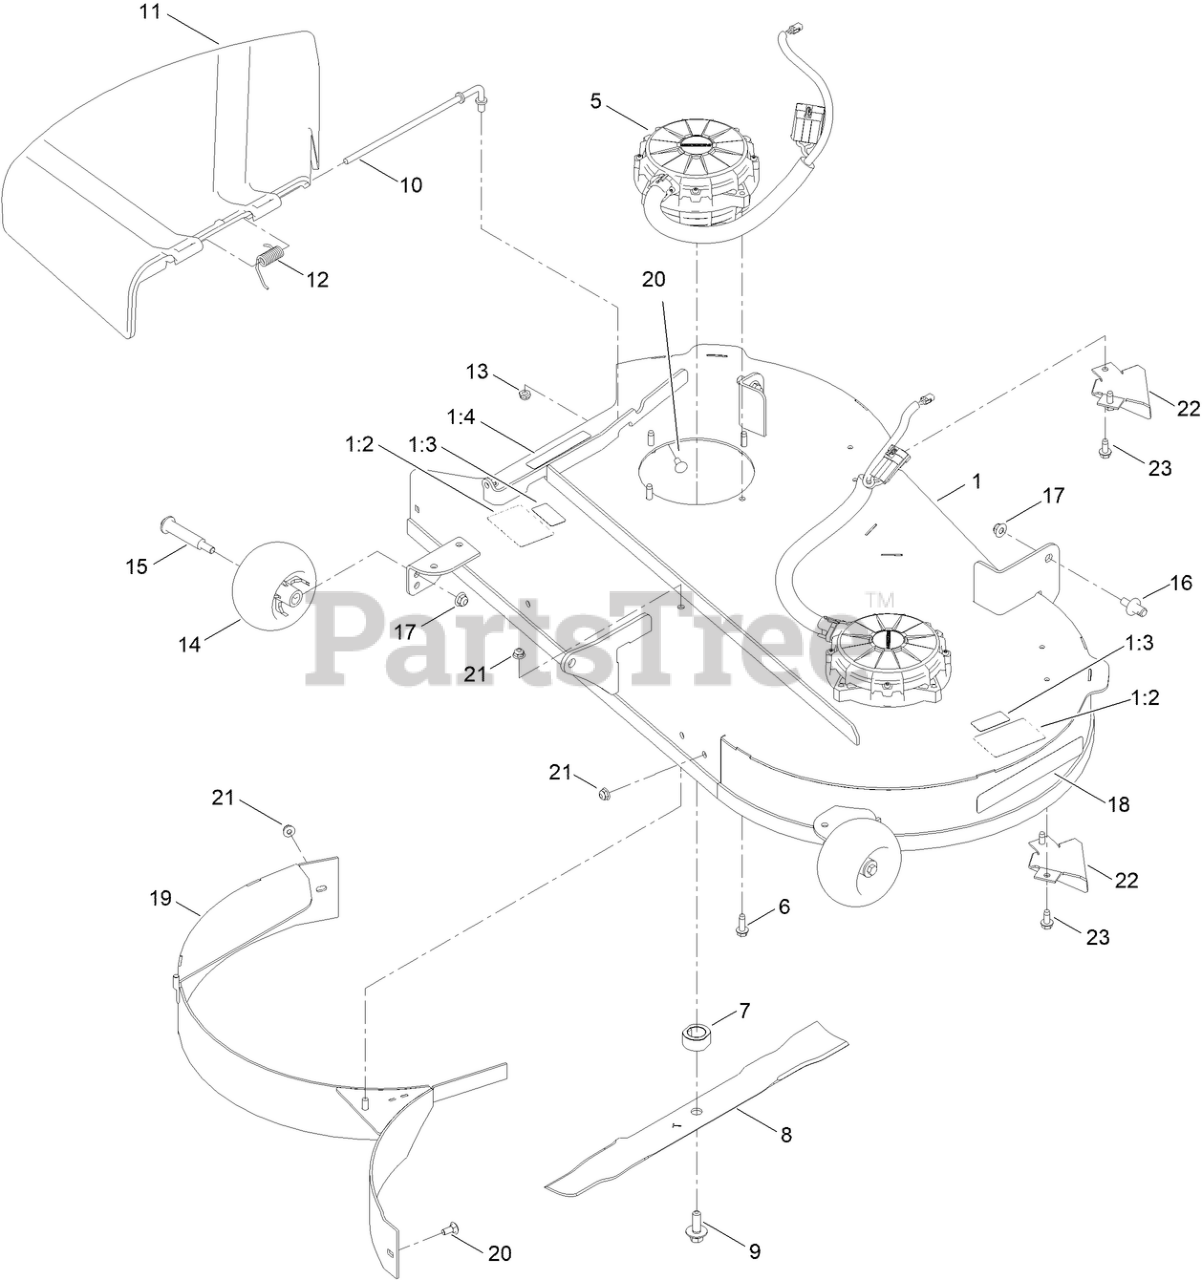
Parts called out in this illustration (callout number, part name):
1	42 IN DECK AND DECAL ASM
1:2	DECAL-DANGER, DECK
1:3	DECAL-NO SPRAY
1:4	DECAL-DANGER
5	MOTOR-DECK
6	SCREW-THD ROLL, HWH
7	DRIVER-BLADE
9	BOLT-BLADE, SEMS
10	ROD-PIVOT
11	DEFLECTOR-DISCHARGE
12	SPRING-TORSION
13	NUT-HEX
14	ROLLER-SCALP, ANTI
15	BOLT-SHOULDER
16	PIN-DECK
17	NUT-HF, NI
19	BAFFLE-RECYCLING [WELDED][BLACK]
20	BOLT-CARR
21	NUT-HF
22	KICKER-FLANGED
23	SCREW-HWHTF
